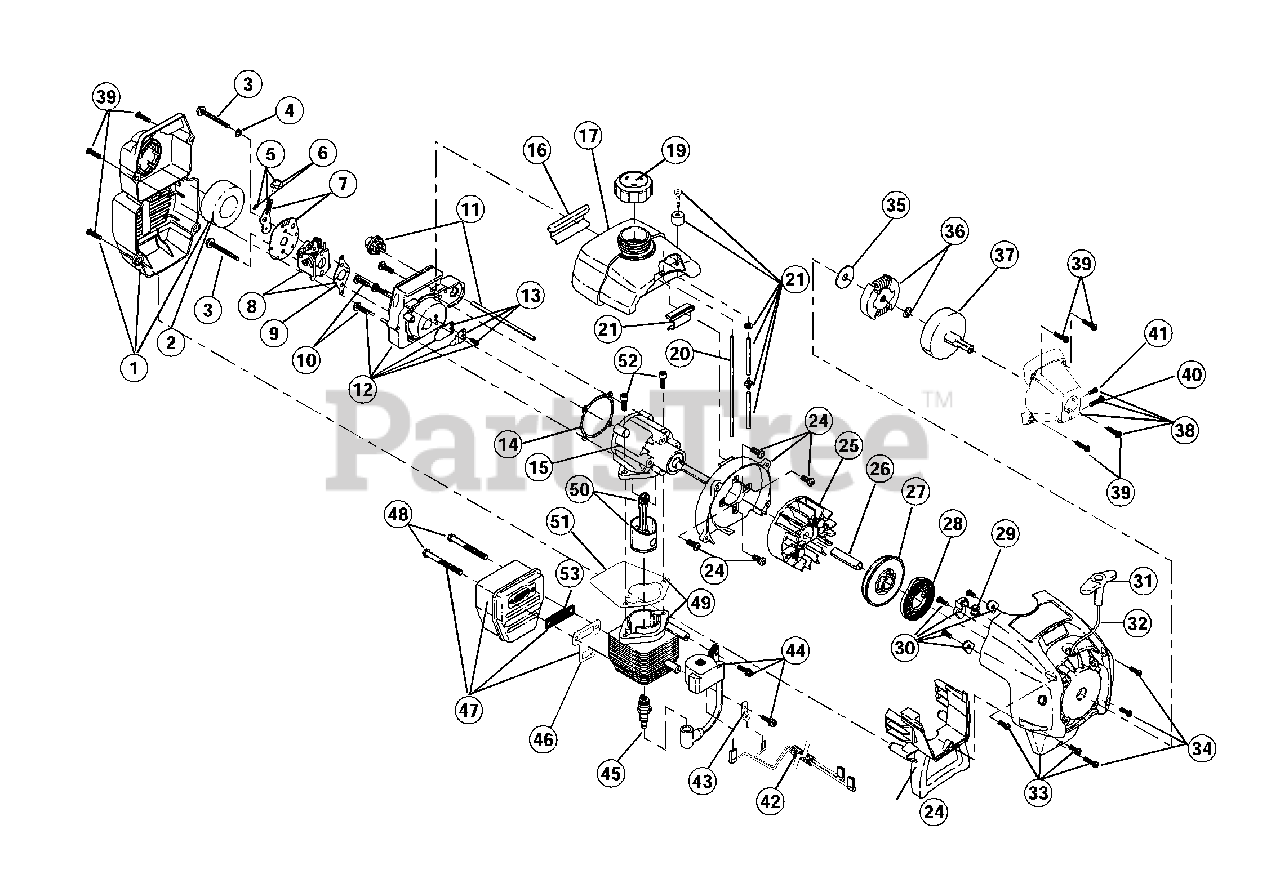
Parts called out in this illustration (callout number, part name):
1	Air Cleaner/Muffler Cover Assembly
2	Air Cleaner Filter
3	Carburetor Mounting Screw Assembly
4	Wavey Washer
5	Choke Lever Assembly
6	Choke Knob and Screw
7	Choke Lever and Plate
8	Carburetor Assembly
9	Carburetor Gasket
10	Carb Mount Screw
11	Primer and Hose Assembly
12	Carb Mount Assembly
13	Reed Assembly
14	Carburetor Mount Gasket
15	Crank Case Service Assembly
16	Rear Mounting Pad
17	Fuel Tank Assembly
18	Fuel Cap Assembly
19	Fuel Return Line
20	Fuel Line Assembly
21	Front Mounting Pad
22	Shroud Assembly
23	Shroud Screw
24	Shroud Extension and Stand
25	Flywheel Assembly
27	Recoil Pulley Assembly
28	Recoil Spring
29	Rope Guide
30	Pulley Retainer Assembly
31	Pull Handle
33	Starter Housing Assembly
34	Housing Screw
35	Clutch Washer
36	Clutch Rotor Assembly
37	Clutch Drum Assembly
38	Clutch Cover Assembly
39	Cover Screw
40	Clamping Screw
41	Anti-Rotation Screw
42	Wire Leads and Sleeve
43	Ground Tab
44	Module Assembly
45	Spark Plug
46	Exhaust Gasket
47	Muffler Assembly
48	Muffler Mounting Bolt Assembly
49	Cylinder Assembly
50	Piston and Rod Assembly
51	Cylinder Gasket
52	Cylinder Bolt
53	Spark Arrestor Screen
